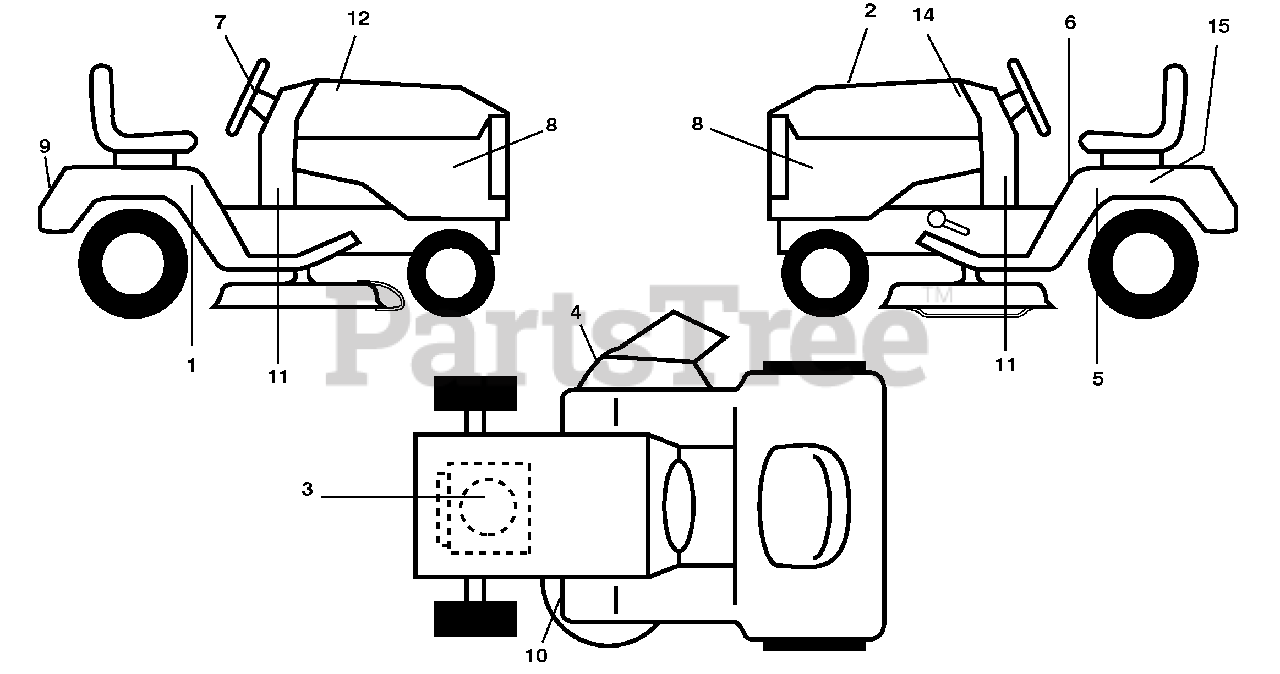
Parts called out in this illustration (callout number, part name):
1	Decal, Fender RH
2	Decal, Replacement
3	Decal, Engine HP
4	Decal Warning
5	Decal, Fender LH
6	Decal, Fender Danger Eng/Fr
7	Decal Ins Str Wh
8	Decal, Side Panel
9	Decal, Fender
10	Decal, V-Belt Sch.
11	Decal, Lower Dash
12	Decal, Hood RH
14	Decal, Hood LH
15	Decal, Caution, Battery
15	Decal, Bypass
15	Decal, Handle Lft Height Adj.
15	Pad Footrest LH
15	Pad Footrest RH
15	Manual, Operator's (E&F)
15	Manual, Parts (E&F)
